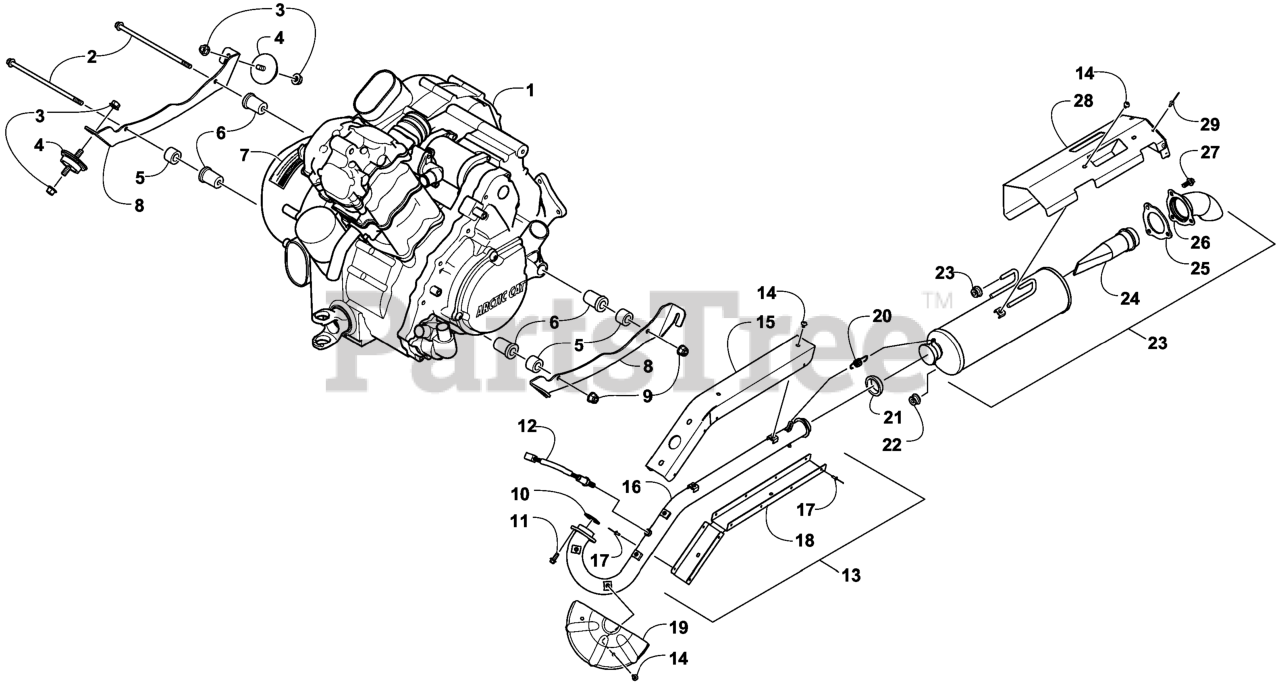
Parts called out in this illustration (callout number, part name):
2	BOLT-HFH
3	NUT-HHF
4	MOUNT-ENGINE
5	SPACER-ENGINE MOUNT
6	Bushing
7	DECAL-WARNING, CLUTCH COV
8	BRACKET-ENGINE, RH
8	BRACKET-ENGINE, LH
10	GASKET-EXHAUST PIPE
11	SCREW-HFH
12	GUIDE-BELT
13	PIPE-EXHAUST
14	SPROCKET,GEARBOX 5 SPEED
15	SHIELD-PIPE, UPPER REAR
16	Pipe, Exhaust
18	SHIELD-PIPE, LOWER
20	SPRING-EXTENSION
21	SEAL-EXHAUST
22	GROMMET-EXHAUST HANGER
23	MUFFLER ASM
24	SPARK ARRESTER
25	GASKET-SPARK ARRESTER
26	TAIL PIPE ASM
27	SCREW-HFH
28	SHIELD-MUFFLER
29	BELT,COG
